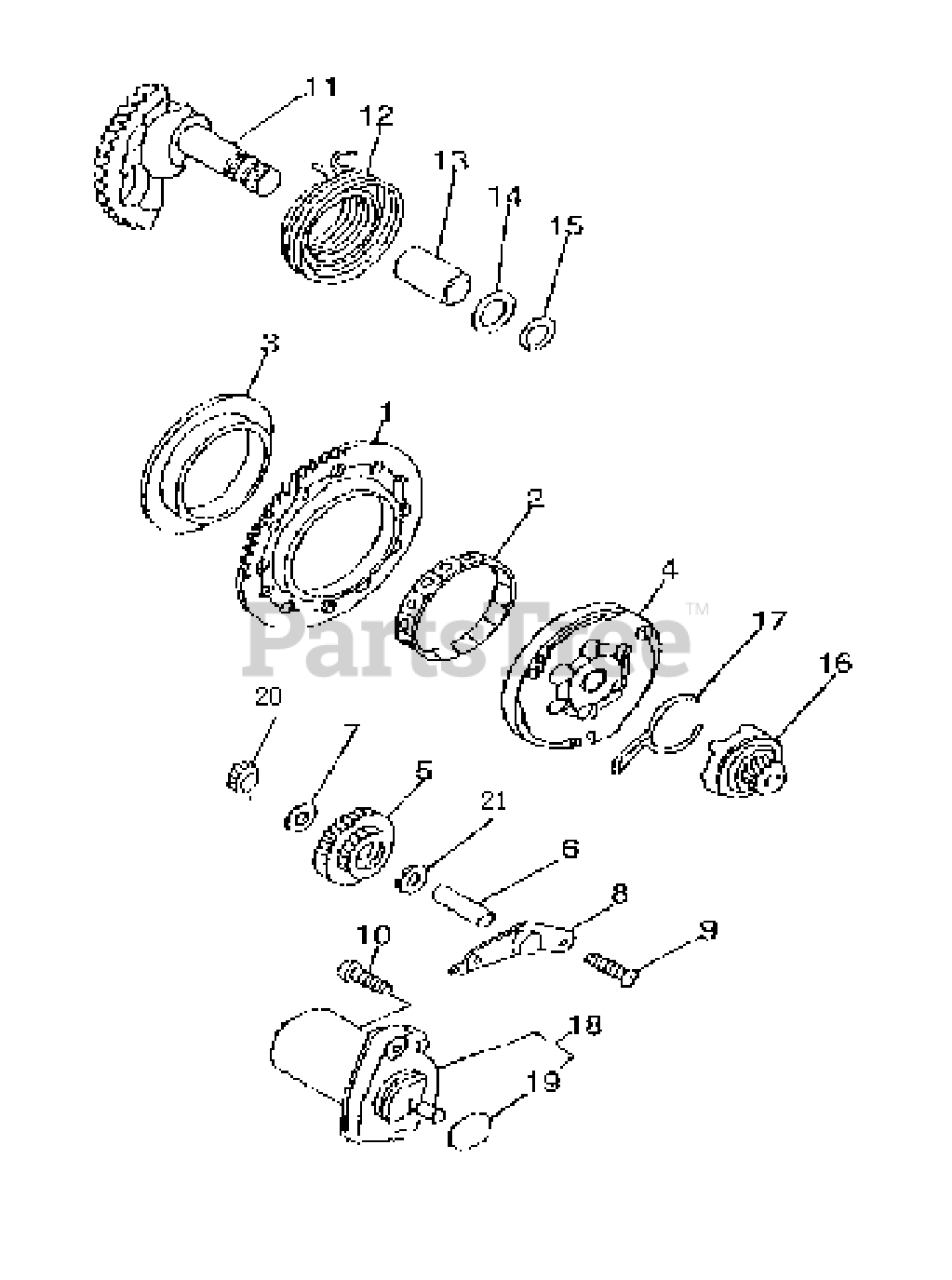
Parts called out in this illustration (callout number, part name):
1	START GEAR ASSY
2	NEEDLE BEARING
3	THRUST WASHER
4	START CLUTCH ASSY
5	IDLE GEAR
6	IDLE GEAR SHAFT
7	PLATE WASHER
8	IDLE GEAR HOLDER
11	SHAFT, KICK STARTER
14	WASHER, KICK STARTER
15	CIRCLIP
16	KICK PINION ASSY
18	STARTING ASSY
19	O-RING
20	NEEDLE BAREING
21	PLATE WASHER
